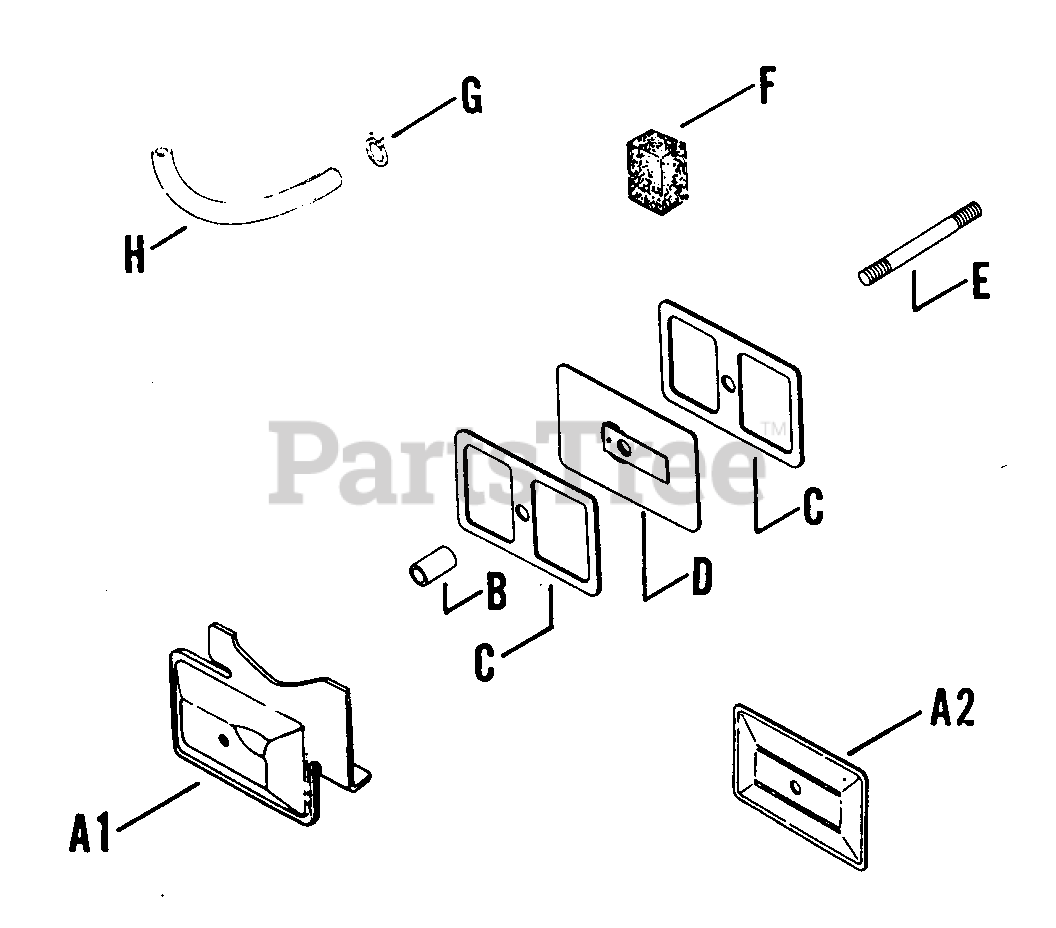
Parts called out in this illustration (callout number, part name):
A1	COVER - USE 230774
B	SEAL, BREATHER
D	BREATHER - DISCONTINUED
E	STUD,1/4-20x3-9/16"
F	FILTER, BREATHER
